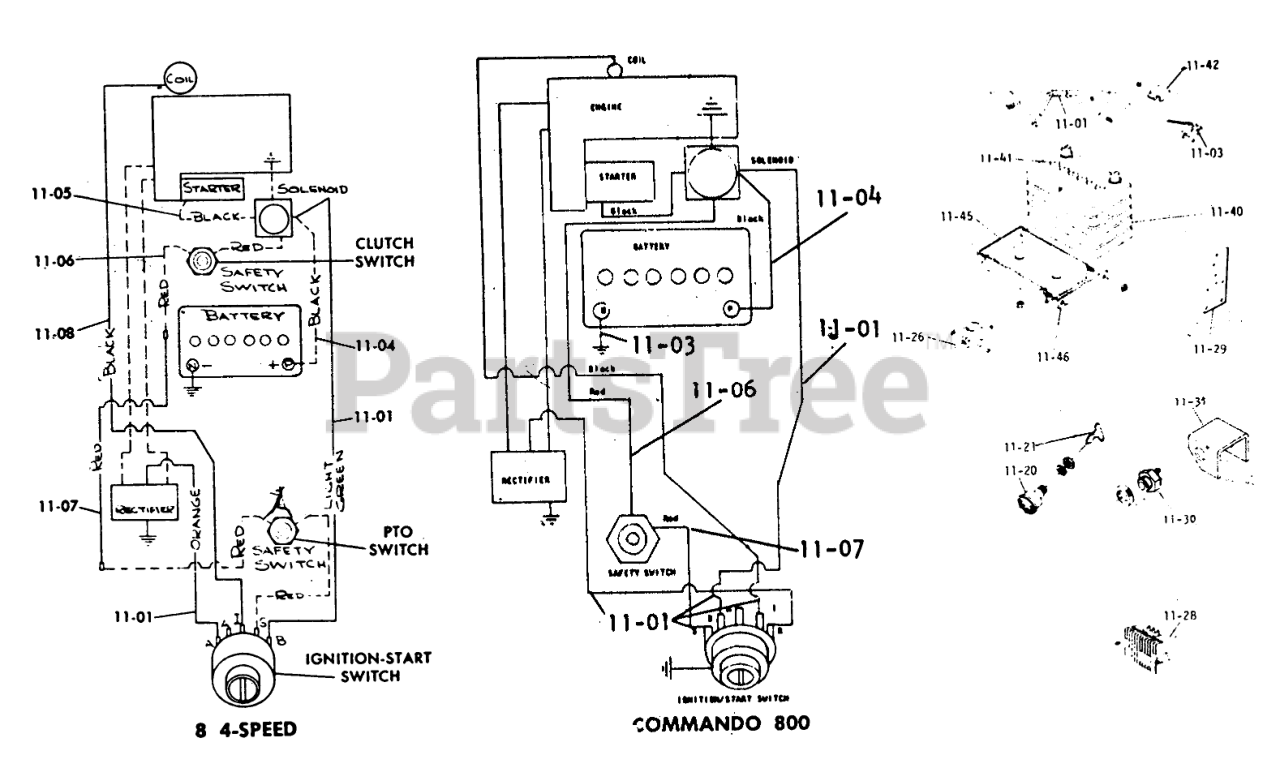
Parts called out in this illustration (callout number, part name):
11-01	Harness-Wiring
11-02	Grommet
11-03	Wire
11-04	Wire
11-05	Wire
11-06	WIRE ASSY
11-07	Wire Assy.
11-20	Switch-Ignition
11-21	Key-EL
11-26	Solenoid
11-28	REGULATOR-RECTIFIER
11-29	PLATE COIL & SOL MTG
11-30	SWITCH SAFETY
11-31	Bracket
11-40	Battery
11-45	Battery Box
11-46	LINK BATTERY CLAM R
